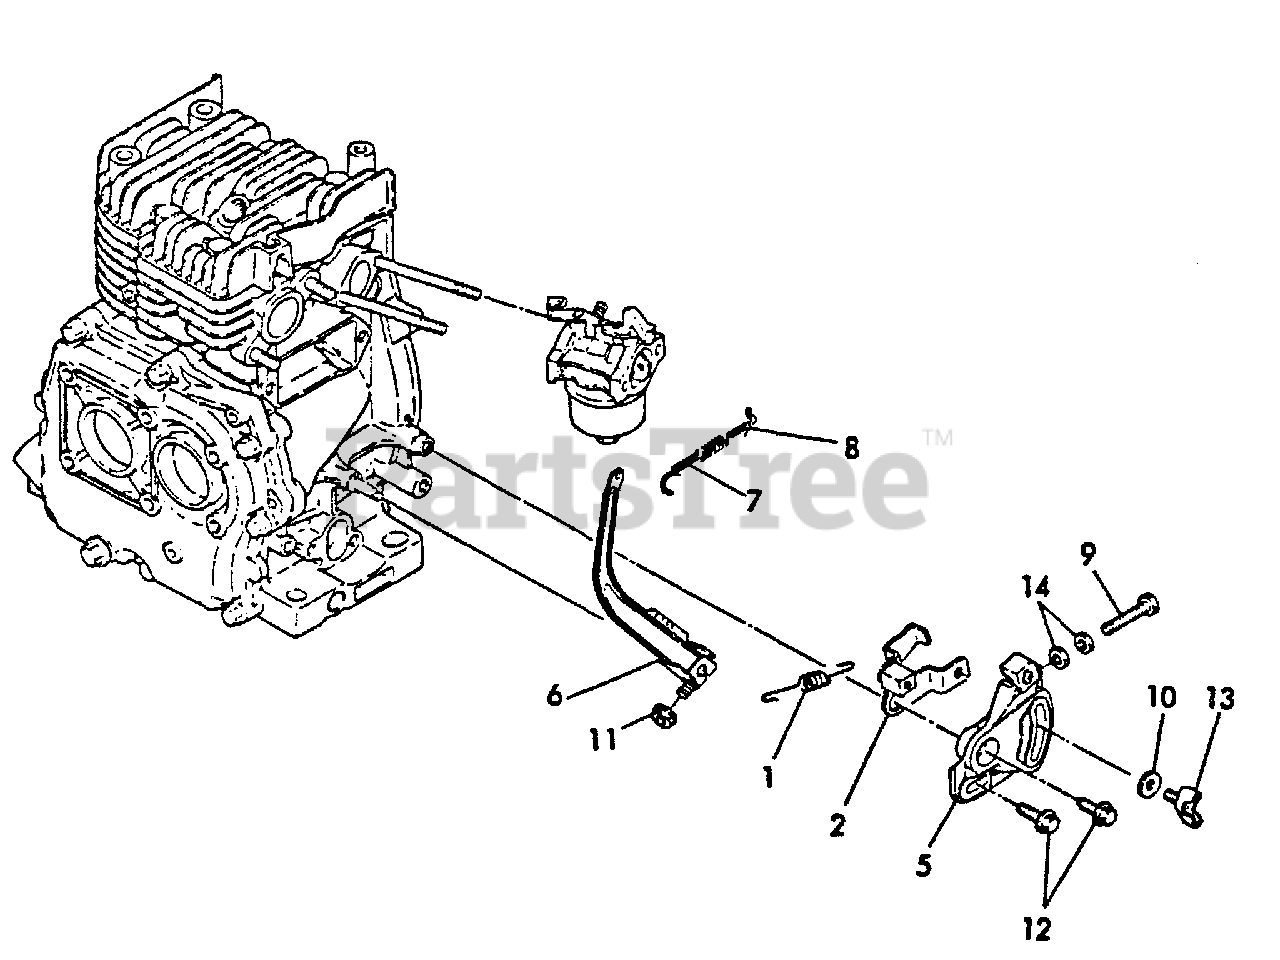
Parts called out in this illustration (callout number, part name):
1	SPRING, REGULATOR
2	HANDLE, REGULATOR
5	BRACKET, REGULATOR
6	LEVER, GOVERNOR
7	LINK, THROTTLE
8	SPRING
9	BOLT
10	WASHER
11	NUT - 6 -- FLANGE
12	BOLT - 6X20
13	THUMBSCREW
14	LOCKNUT - 6 -- PLATED
